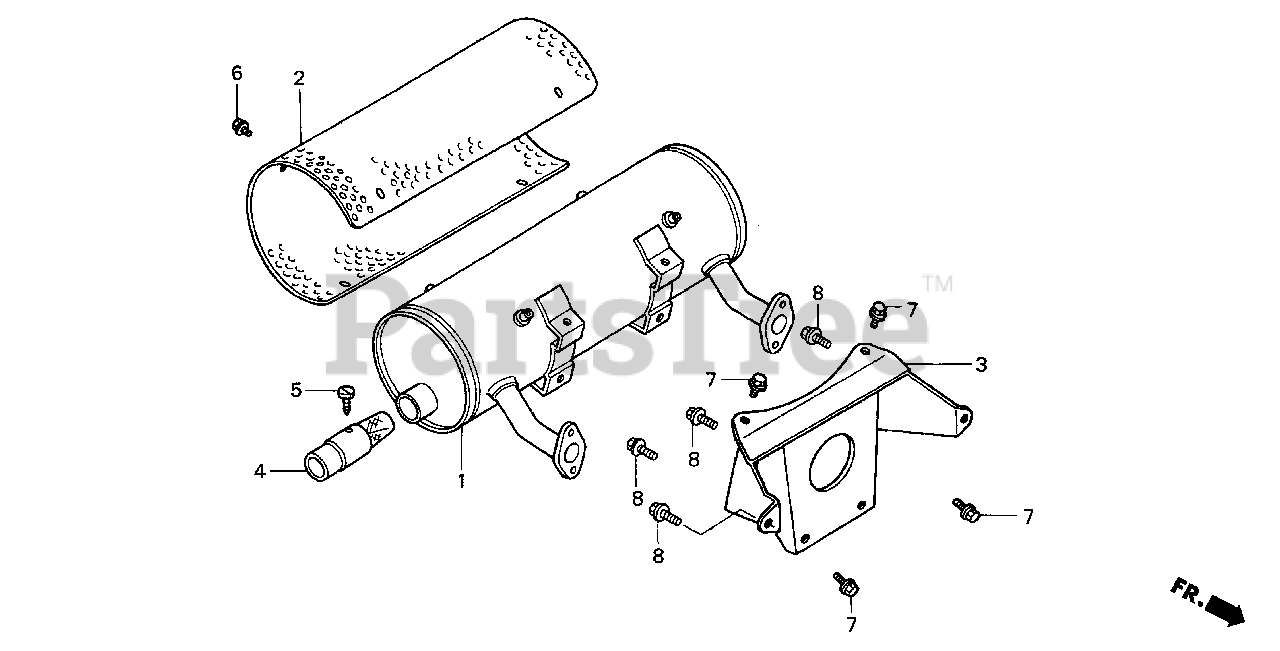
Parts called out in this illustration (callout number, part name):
1	MUFFLER (HIGH-R)
2	PROTECTOR, MUFFLER
3	STAY, MUFFLER (HIGH)
4	ARRESTER, SPARK
5	SCREW (NELSON)
6	BOLT, FLANGE (6X8)
7	BOLT, FLANGE (8X14)
8	BOLT, FLANGE (8X20)
